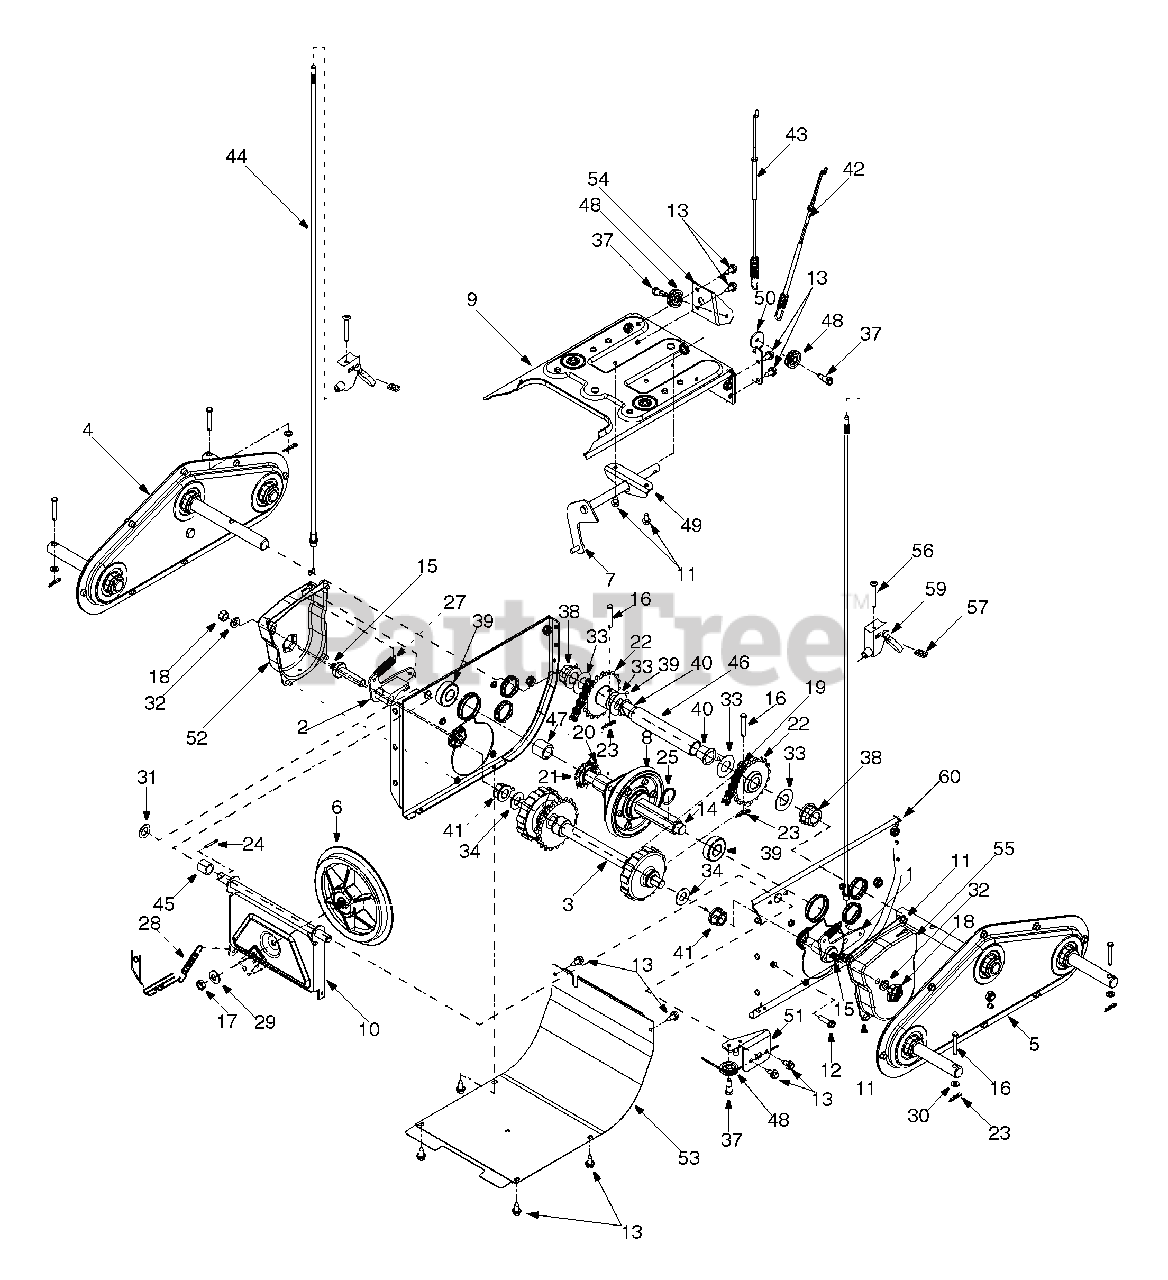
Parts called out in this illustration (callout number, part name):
1	Dogg Assembly: RH
2	Dogg Assembly: LH
3	Shift Assembly: Steerable Drive
4	Chain Case Assembly: RH
5	Chain Case Assembly: LH
6	Friction Wheel Disc Assy.
8	Wheel Assembly, Friction
11	Hex Washer Screw 1/4-20 x 0.5"
12	Hex Washer Screw 1/4-20 x 1.0"
13	Hex Washer Screw 1/4-20 x .625"
14	Drive Shaft
15	Actuator Shaft
17	Jam Nut 3/8-24 Gr.8
18	Hex Nut: 3/8-16
21	Sprocket: 19T
23	Cotter Pin
24	Cotter Pin
25	Snap Ring
27	Extension Spring
28	Extension Spring
29	Bell Washer
30	Flat Washer
31	Flat Washer
32	Lock Washer
33	Flat Washer
34	Flat Washer
37	Shoulder Screw
38	Hex Flange Bearing
39	Ball Bearing
40	Flange Bushing
41	Hex Flange Bearing
42	Auger Clutch Cable
43	Drive Clutch Cable
44	Steering Cable
46	Support Tube: Axle
48	Roller Cable
58	Cable Tie
59	Turn Trigger
